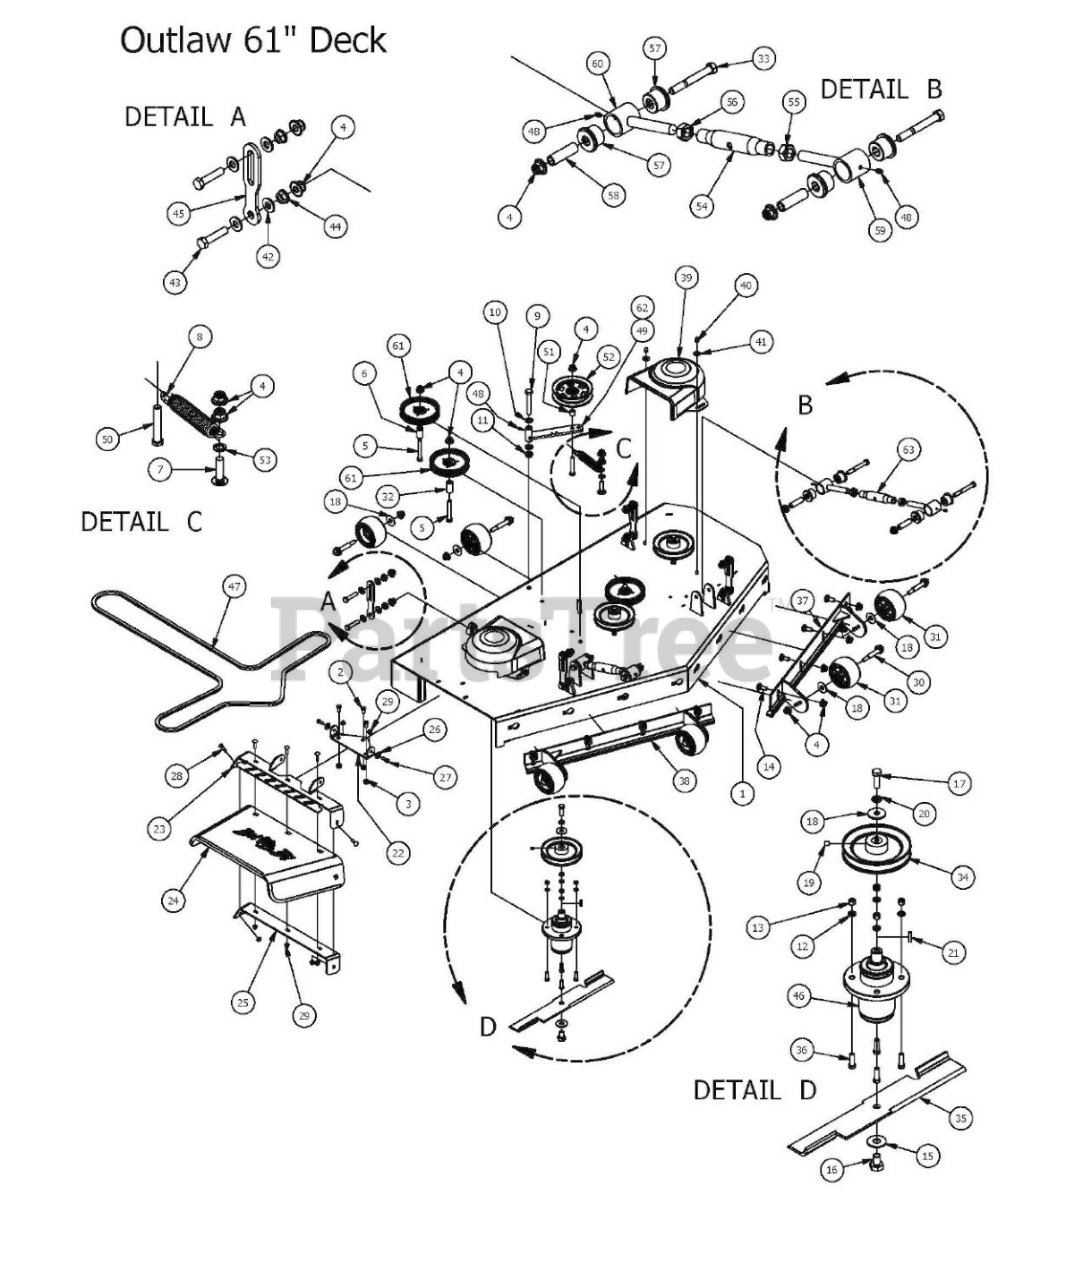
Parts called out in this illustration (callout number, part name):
1	2015 61" Deck
2	3/8" x 3/4" Hex Bolt
3	3/8" Flange Nut
4	1/2-13 Nylon Flange Nut
5	1/2 x 3 1/2 Flange Bolt Grade 8
6	Idler Pulley Standoff
7	1/2 x 2" Carriage Bolt
8	2015 Deck Idler Spring
9	5/8" x 4" Hex Bolt
10	.630 ID Plastic Washer
11	5/8-11 Nylon Insert Jam Half Nut
12	3/8 Lockwasher Zinc
13	3/8-16 Hex Nuts Zinc
14	1/2" x 1 1/4 Carriage Bolt
15	5/8" Flat Washer
16	5/8" x 1 1/2" Grade 8 Hex Bolt (Fine)
17	1/2"-20 x 1 1/2 - Grade 5 Fine Thread Bolt
18	1/2" Belleville Washer
19	5/16 Set Screw
20	1/2" Lock Washer
21	1/4" x 1" Key
22	Discharge Chute Hanger (deck mounted)
23	60" Discharge Chute Upper Hanger
24	Rubber Discharge Chute
25	60" Discharge Lower Bracket
26	.360 ID Plastic Washer
27	5/16" x 1" Bolt
28	5/16" x 1 1/4" Carriage Bolt
29	5/16" Nylock Flange Nut Zinc
30	Deck Wheel Bolt
31	Anti-Scalp Roller
32	1 3/4" Pulley Spacer
33	1/2" x 4" Bolt (Grade 8)
34	6 1/4" Drive Pulley
35	61 inch Fusion Blade
36	3/8" x 1 1/4" Hex Bolt
37	61 Deck Adustable Front (Left)
38	61 Deck Adustable Front (Right)
39	Pulley Cover
40	Acorn nut-pulley Cover
41	.360 ID Plastic Washer-Black
42	.505 Nylon Spacer
43	1/2-13X 2-1/4 GR Hex Bolts.
44	1/2" Flange Nut
45	Deck Hanging Tab
46	OUTLAW SPINDLE ASSEMBLY
47	B178 Belt For 61 Inch Outlaw
48	1/4" Press in Grease Fitting
49	Deck Idler
50	1/2-13 x GR 5 Hex Bolt Zinc
51	Spacer 3/4 OD x 1/2 ID x 314 Length
52	5" Idler Pully
53	.517 Square Hole Round Washer
54	2015 Outlaw Toplink Body
55	3/4-10 Left-Handed Hex Nuts Zinc
56	3/4-10 Hex Nuts Zinc
59	Turn Left-Handed
60	Right-Handed End
61	5-3/4 Idler Pulley-Capitol Stampings
62	Deck Idler Assembly - Includes parts: 4,48,49,50,51,52
63	Turnbuckle Assembly
